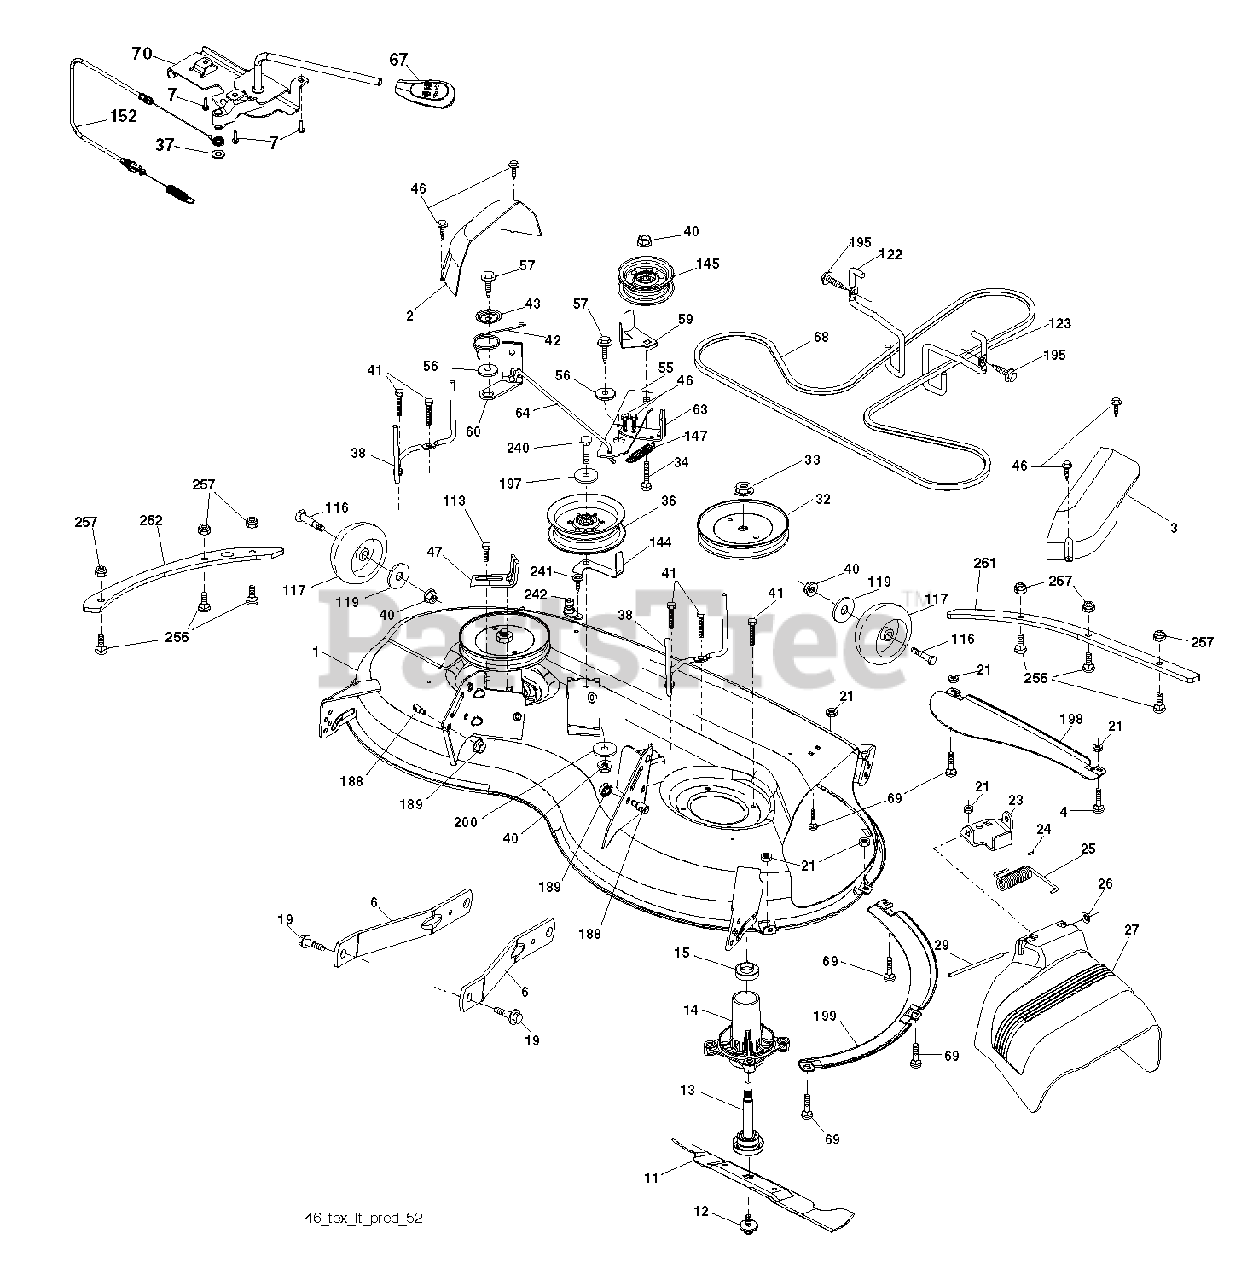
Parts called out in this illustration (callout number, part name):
1	DECK SVC 46"583900906X421
2	COVER.MANDREL.LH.46"
3	COVER.MANDREL.RH.46"
4	BOLT
6	ARM.SUSPENSION.MOWER.R
7	SCREW.#10 X 0.750.BOS (2 2)
11	BLADE.MOWER.46".HI.LIFT
12	Screw, 7/16 X 20 X 1"
13	Mandrel Assembly, Non-Greaseable
14	HOUSING.MANDREL.4PT.
15	Extended Mandrel Bearing, Top
19	BOLT.SHOULDER
21	LOCKNUT
23	BRKT.DEFLECTOR.38"2005+
24	CAP-SLEEVE LT
25	SPRING.TORSION.DEFLECT
26	NUT PUSH M
27	SHIELD.DEFLECTOR.MOWER.46"BLAC
29	ROD.HINGE
32	PULLEY.MANDREL.5.438.PD
33	NUT.FLANGE.LOCK.TOP
34	BOLT.3/8-16X1.50
36	PULLEY.IDLER.2006
38	KEEPER.BELT.MANDREL.PULLEY
40	NUT LOCK FLG 3/8-16 UNC
41	Hex Washer Head Bolt, .313-18 X 1.19
42	SPRING.TORSION.BRAKE
43	SRPING.TORSION.RETAINE
46	SCREW.1/4-20X5/8
47	BRKT.CLUTCH.CABLE
55	IDLER.ARM
56	SPACER.RETAINER
57	SCREW 3/8-16X1
59	GUARD, BELT
60	ARM BRAKE MOWER RH 38"
64	LINKAGE BRAKE
67	HANDLE.CLUTCH.CABLE.LT
68	V-BELT
69	BOLT
70	CLUTCH.ASM.MANUAL.YT.PREDATORQ
113	BOLT.5/16HEX.WHS.HD
116	BOLT M
117	WHEEL.GAGE.HALF.SPOKED
119	WASHER
122	KEEPER BELT ENGINE LH
123	KEEPER BELT RH
144	KEEPER.BELT.MOWER
145	PULLEY.IDLER.48"PRIMARY
147	SPRING RETURN
152	CABLE.MECHANICAL.CLUTCH
188	STUD.FASTNER.W/ANTI-ROTATE
189	NUT LOCK HEX FLANGE 5/16-18
195	SCREW, 3/8-16X3/4
197	WASHER
198	BAFFLE CENTER FRONT
199	BAFFLE FRONT RH
200	WASHER.13/32 X 1 X 1/2.11GUARD
240	BOLT-HEX EAK
241	SCREW.TT.#10-32X.5.3/8.FLANGE
242	PORT.WASHOUT
256	Buttonhead Screw, 5/16-18
257	NUT T
261	Reinf Deck Plate, Pnt 46" Edip
262	Side Reinforcement Plate, 46" Bolt-on
